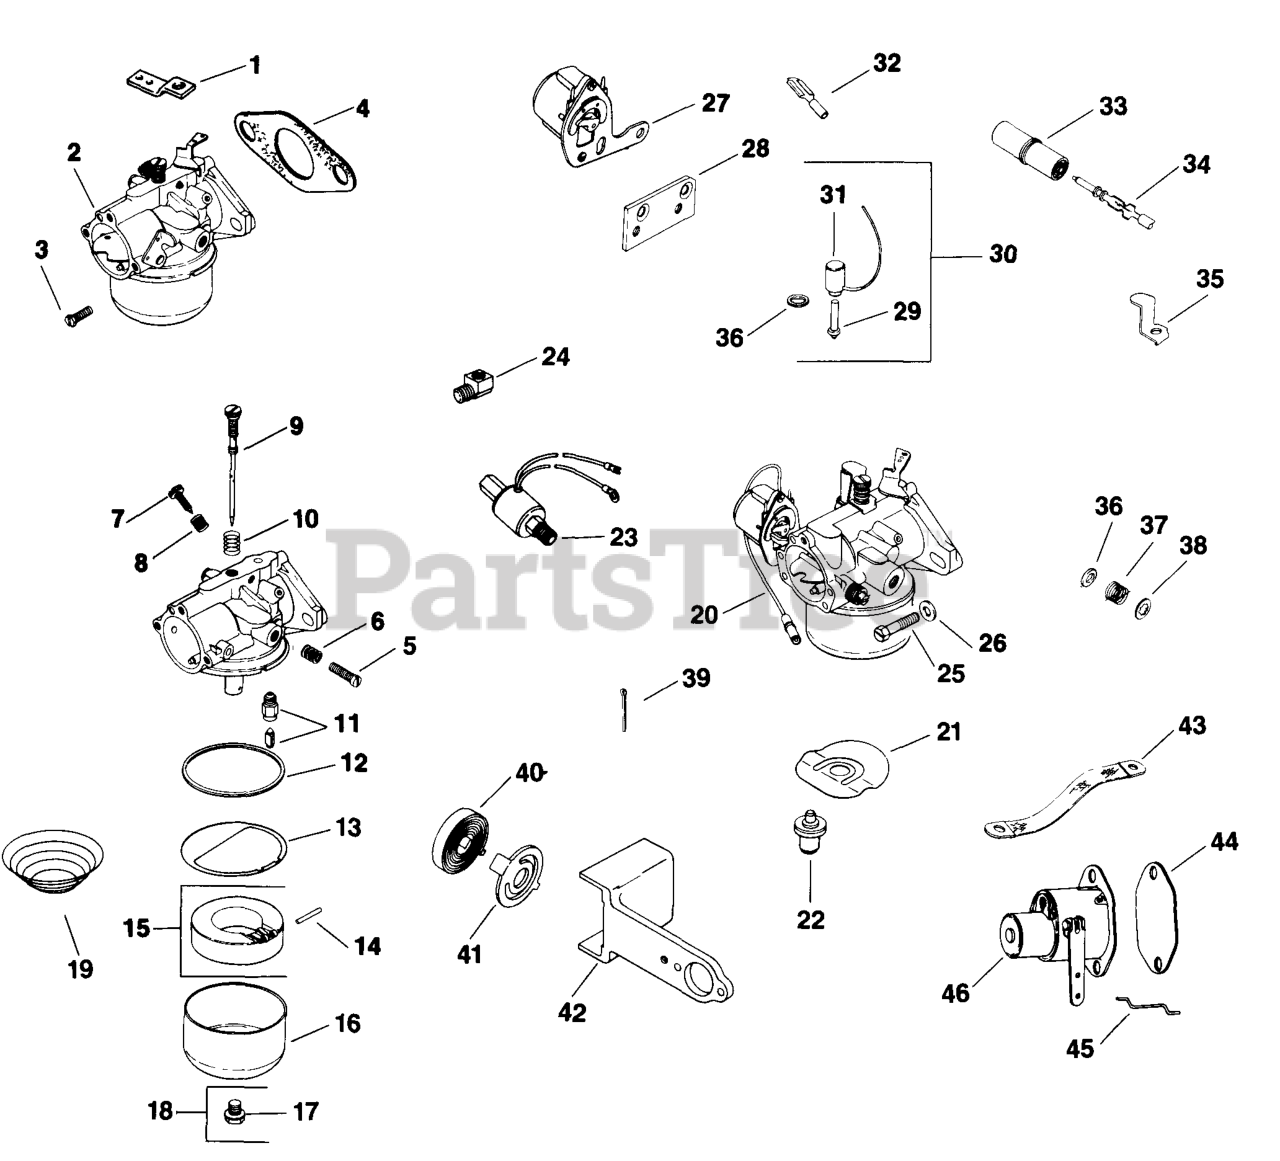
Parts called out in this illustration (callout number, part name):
2	CARBURETOR - USE 41 853 08
3	SCREW-DISCONTINUED
5	SCREW, SPECIAL
6	SPRING-(#DSC)
7	SCREW - DISCONTINUED
9	NEEDLE - DISCONTINUED
11	Needle and seat
12	GASKET
14	PIN
15	KIT, FLOAT REPAIR - DISCONTINUED
17	GASKET
18	NUT - DISCONTINUED
